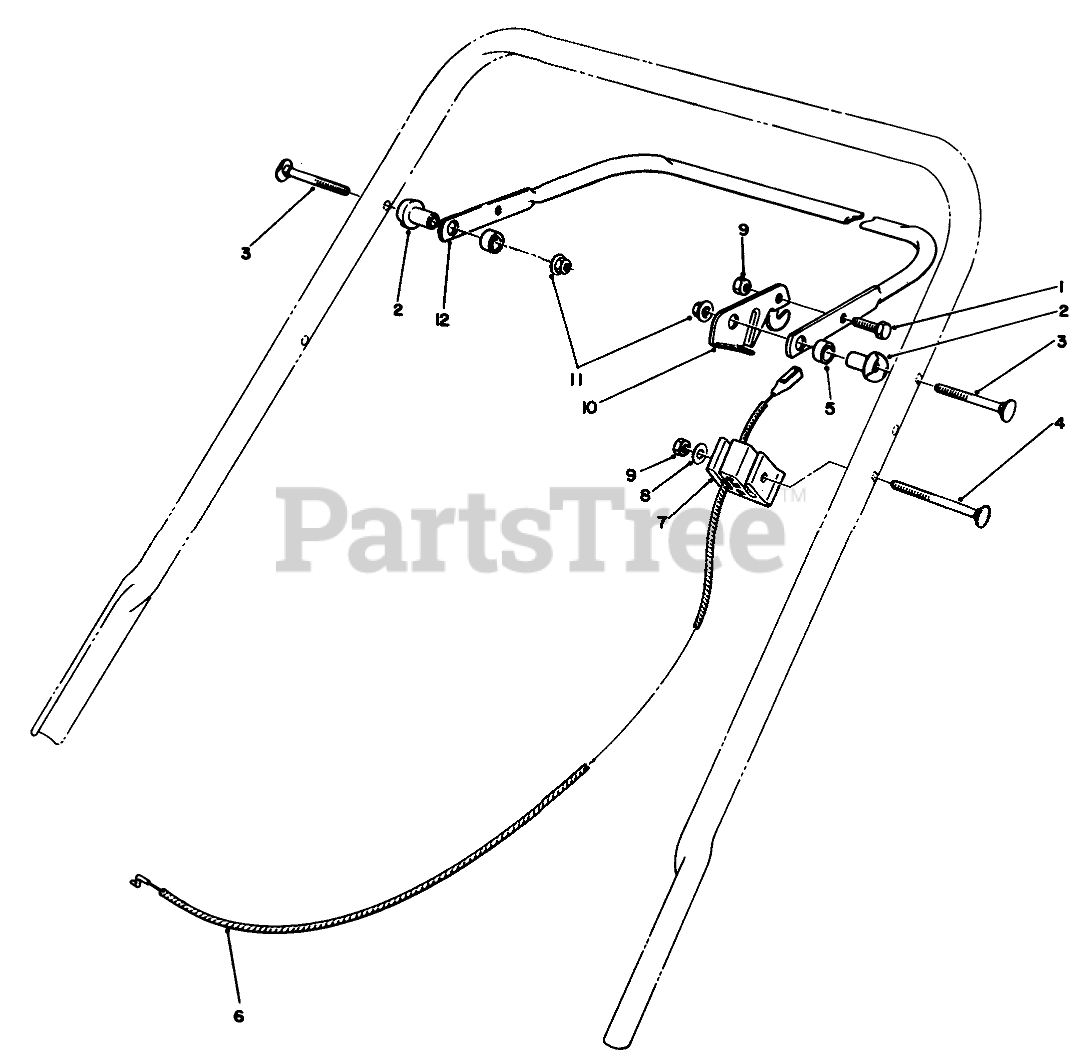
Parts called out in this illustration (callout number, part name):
1	SCREW-HH
2	SPACER-SUPPORT
3	5/16-18 X 2 HNDLE SCREW
4	HANDLE SCREW
5	SPACER-NYLON
6	BRAKE CONTROL
7	SUPPORT-CABLE
8	WASHER-FLAT
9	NUT-LOCK, NI
10	LEVER-CONTROL
11	NUT-LOCK, NI
12	Bar-Control
